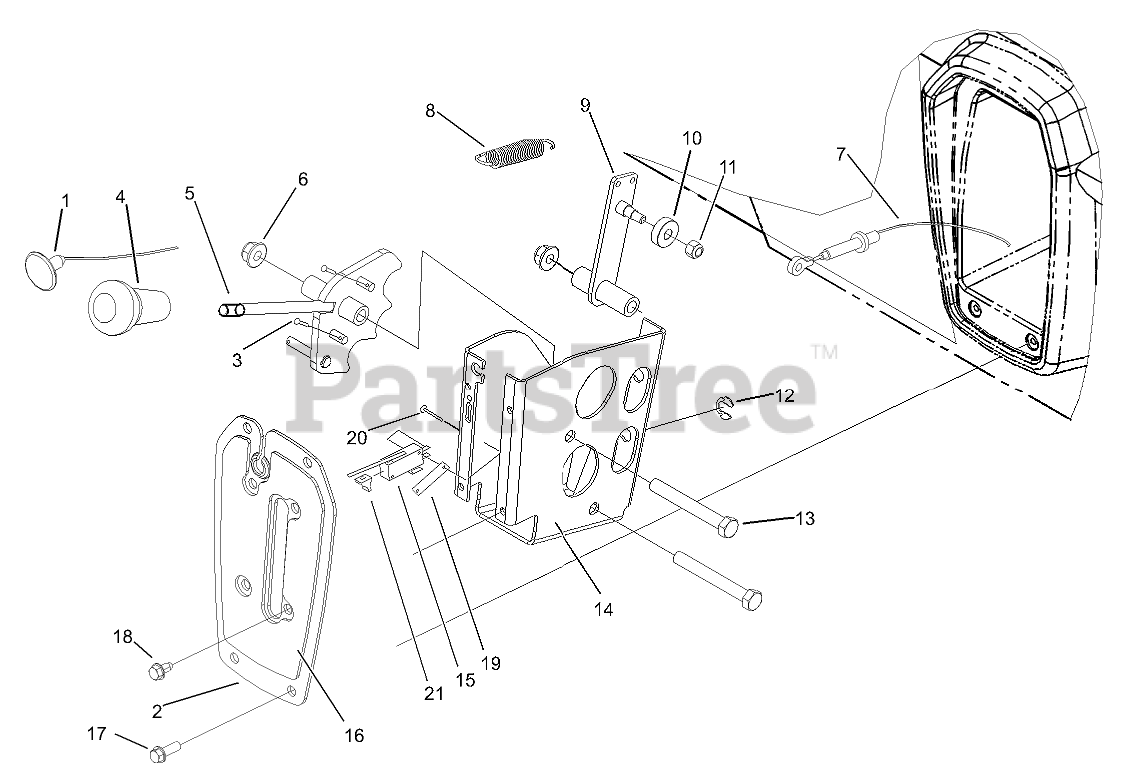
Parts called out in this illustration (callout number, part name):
1	CABLE-CHOKE
2	PLATE-SHIFTER
3	PIN-COTTER
4	KNOB-GRIP, SOFT
5	LEVER-SHIFTER
6	NUT-HF, NI
7	Cable-Shift
8	SPRING-RETURN, PEDAL
9	DETENT
10	BEARING-BALL
11	NUT-LOCK, NI
13	SCREW-HH
14	BRACKET-SHIFT
15	SWITCH-MICRO
16	DECAL-SHIFTER
17	SCREW-HWH
18	SCREW
19	NUT-SPEED
20	SCREW-SPH
21	PLUNGER-SEAL
